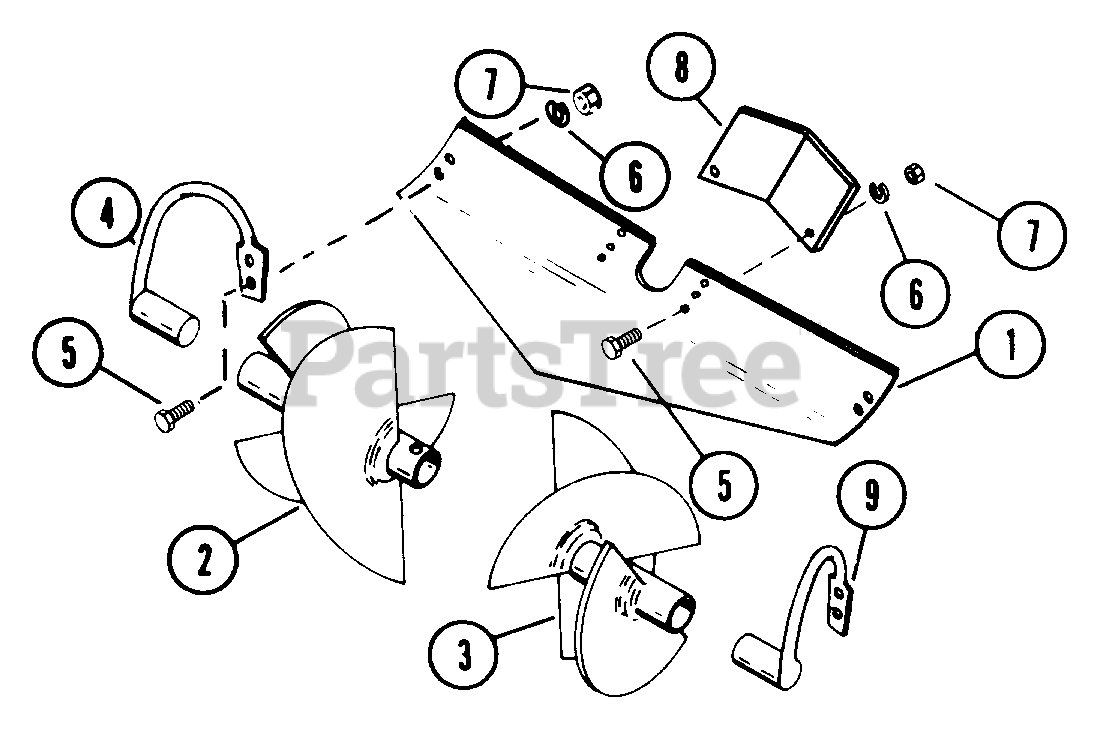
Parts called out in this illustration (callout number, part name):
1	BACK PLATE
2	R H TIL BLADE
3	L H TIL BLADE
4	R. H. MOUNTING BRACKET
5	CAP SCREW, M5 X 0.8 X 20
6	WSHR-LK .250X.077 HVY PL
7	NUT-HEX .250-20 PL
8	ADJUSTMENT PLATE
9	L. H. MOUNTING BRACKET
